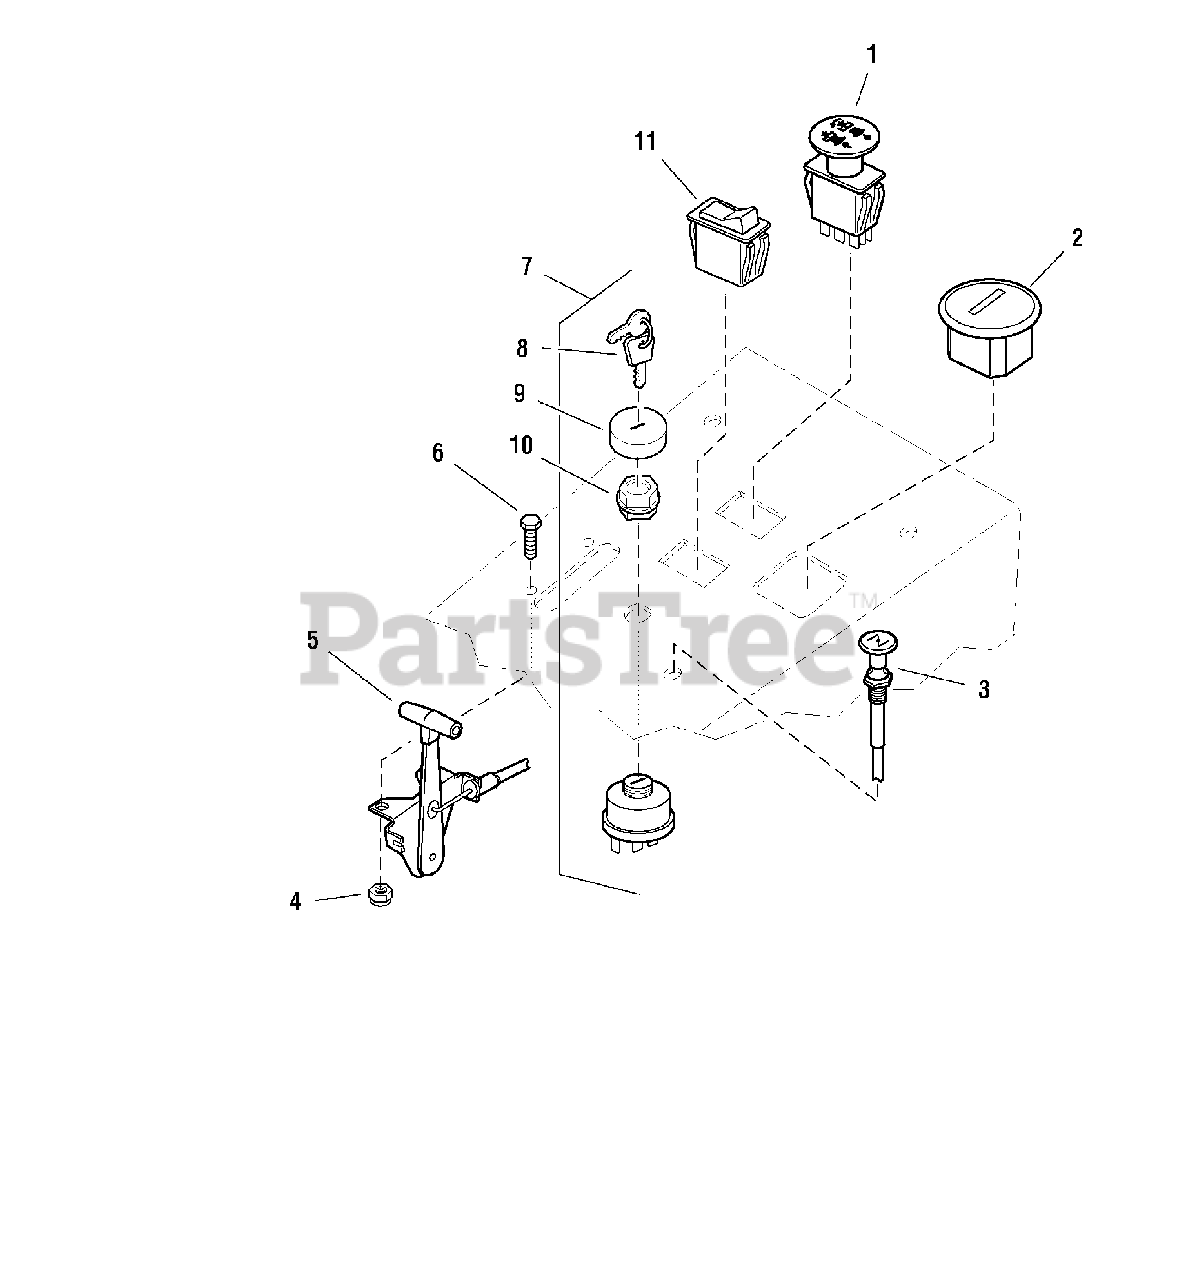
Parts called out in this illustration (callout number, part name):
1	SWITCH, PTO
3	CABLE, Choke Control
4	NUT, Hex, Nylon Lock, 1/4-20
5	CABLE, Throttle Control
6	CAPSCREW, Hex Hd, 1/4-20 x 3/4
7	SWITCH, Ignition, Complete (includes Ref 8-10)
8	KEY, Ignition, Molded (Set of 2)
10	PLASTIC NUT
11	SWITCH, Headlight
